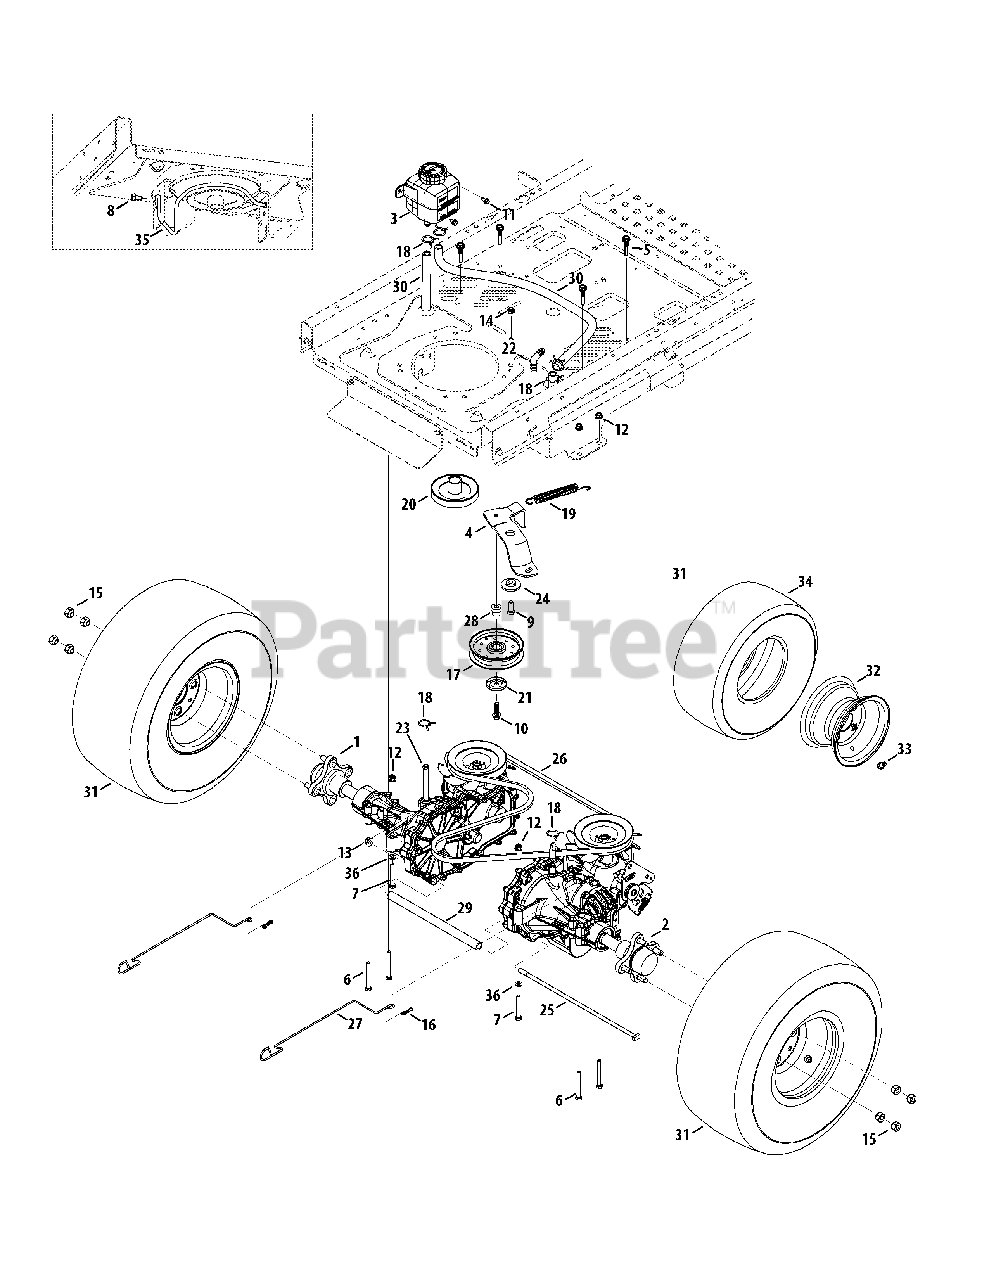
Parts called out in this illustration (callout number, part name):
1	Transmission Assembly, LH
2	Transmission Assembly, RH
3	Expansion Tank Assembly
4	Idler Bracket
5	Keeper Rod, .25 x 1.535
6	Hex Screw, 5/16-18 x 2.75
7	Hex Cap Screw, 5/16-18 x 2.25
8	Hex Washer Screw, 5/16-18 x .750
9	Hex Screw, 3/8-16 x 1.00
10	Hex Washer Screw, 3/8-16 x 1.250
11	Hex Washer Screw, 1/4-20 x .625
12	Flange Lock Nut, 5/16-18
13	Flange Lock Nut, 3/8-16
14	Jam Lock Nut, 3/8-16
15	Lug Nut, 7/16-14
16	Bow-Tie Cotter Pin
17	Idler Pulley, 4.25 Dia.
18	Hose Clamp, .75 Dia. x .312
19	Extension Spring, .75 Dia. x 6.02
20	Engine Pulley
21	Pulley Cap
23	Fitting, 9/16, Barb
24	Shoulder Spacer, .884 x .190
25	Rod, .337 Dia. x 14.75 LG
26	Belt, A-Type x 67.0
27	Bypass Rod
28	Shoulder Spacer
29	Spacer, .75 OD x 11.31 LG
30	Fuel Hose, 1/2 ID
31	Complete Wheel, 20 x 10-8
33	Valve Tubeless
35	Engine Keeper Rod
36	Flat Washer .330 ID x .630 OD
